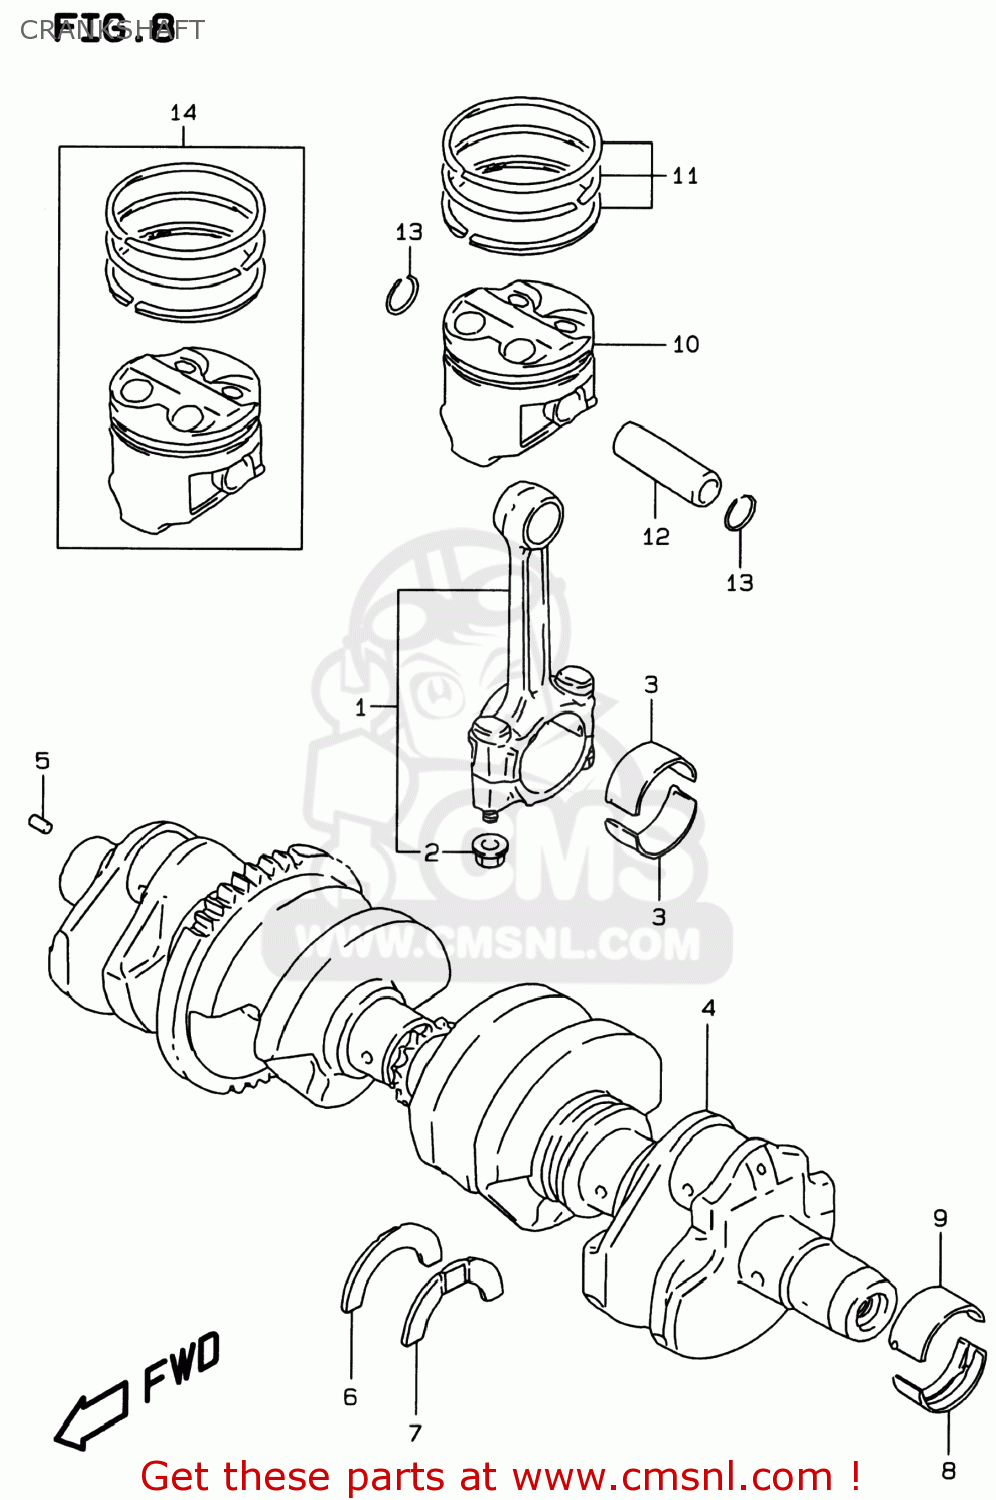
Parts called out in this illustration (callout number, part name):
1	CONNECTING ROD ASSY
2	NUT
3	BEARING,CRANK PIN
4	CRANKSHAFT SET
5	PIN
6	PLATE,CRANK THRUST
7	PLATE,CRANK THRUST
8	BEARING,CRANKSHAFT LWR
9	BEARING,CRANKSHAFT UPR
10	PISTON
11	RING SET,PISTON
12	PIN,PISTON
13	CIRCLIP
14	PISTON SET(OS:0.5)
